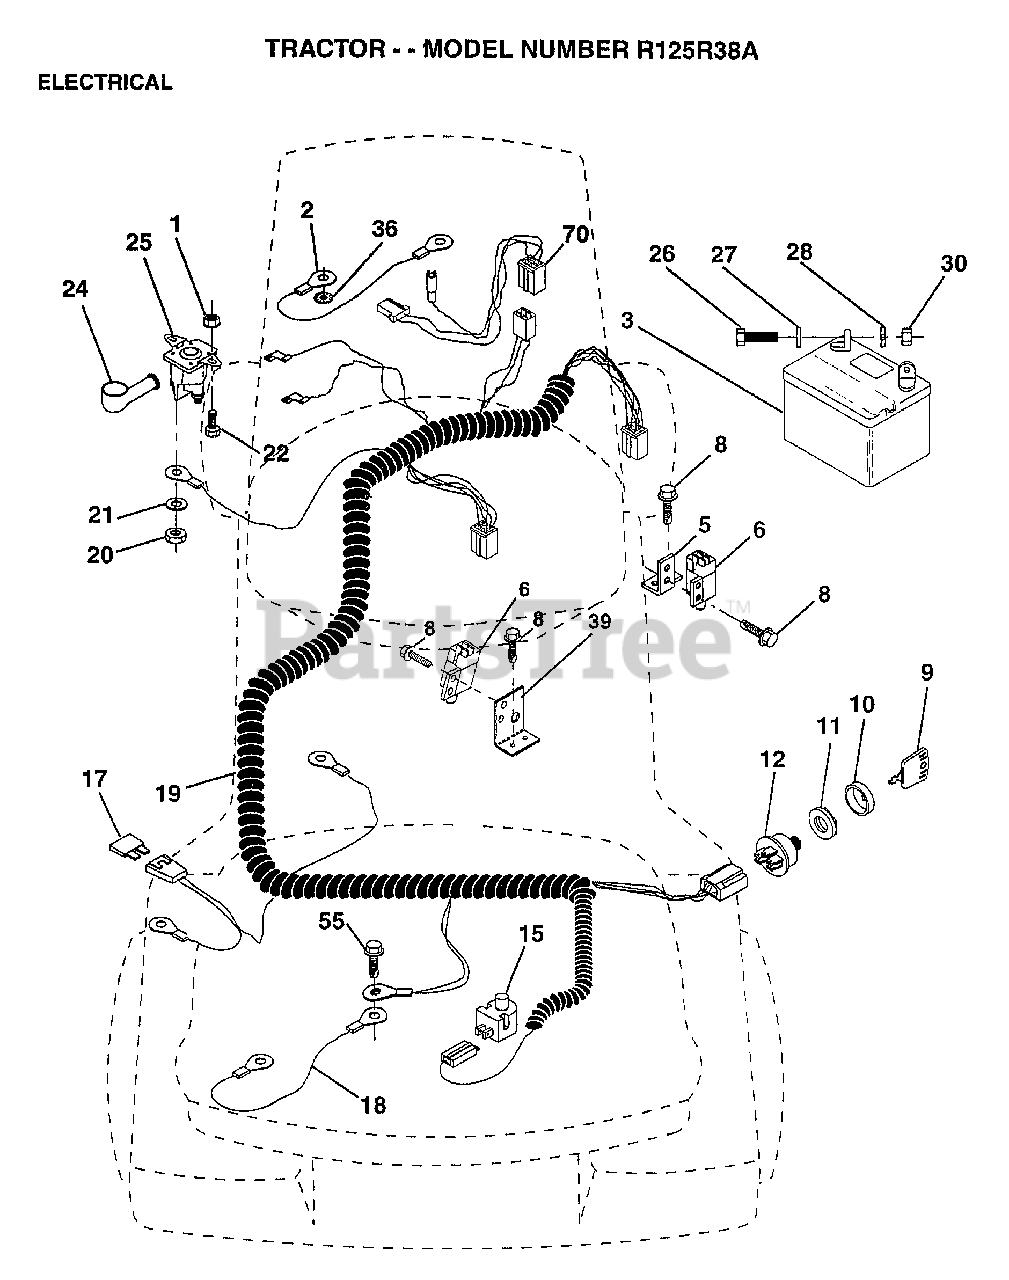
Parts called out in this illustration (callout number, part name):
1	NUT HXKEP 1/4X20
2	CABLE ASM.
4	LOCKNUT
5	BRACKET LT
6	SWITCH INTERLOCKT
7	KEEPER.ACTUAT.LR.
8	SCREW
9	KEY MLD GEN DELTA
10	COVER KEY SWITCH
15	SWITCH SEAT
17	FUSE HYT
18	ASSEMBLY, CABLE
19	HARNESS.IGN.LR.
20	NUT
22	BOLT HXHD FIN
26	BOLT LT
27	WASHER
28	LOCKWASHER
31	HEADLAMP BULB
32	"HARNESS,LIGHT SOC"
33	SWITCH LT
36	LOCKWASHER
39	BRACKET SWT CLUTC
55	SCREW LT
70	HARNESS ENG DUAL
